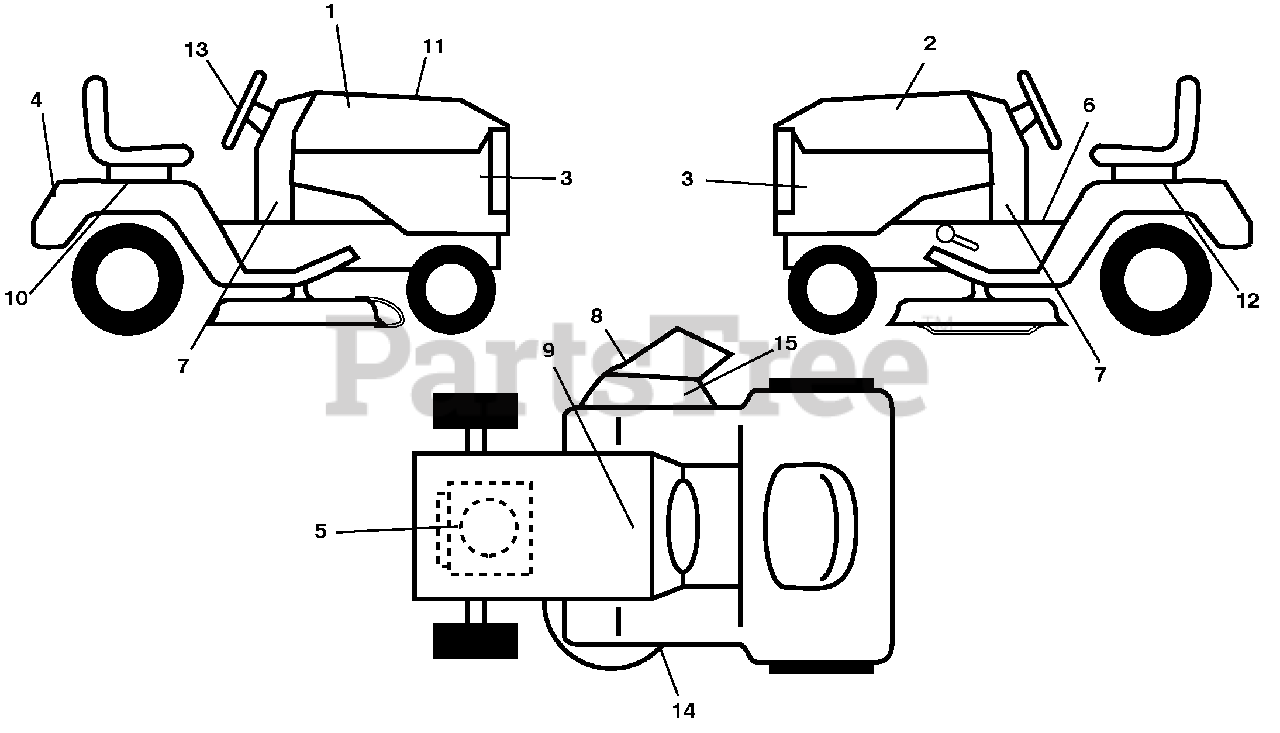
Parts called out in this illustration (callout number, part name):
1	Decal, Hood RH
2	Decal, Hood LH
3	Decal, Side Panel
4	Decal, Fender
5	Decal, Engine
6	Decal, Fender Operator's
7	Decal, Lower Dash
8	Decal, Warning
9	Decal, Battery Danger/Poison
10	Decal, Fender RH
11	Decal, Replacement
12	Decal, Fender LH
13	Decal, Steering Wheel
14	Decal, Mower Schematic
15	Decal, Caution
15	Decal, Bypass
15	Pad, Foot Pedal Control
15	Pad, Footrest, LH
15	Manual, Operator's (Eng/French)
15	Manual, Parts
